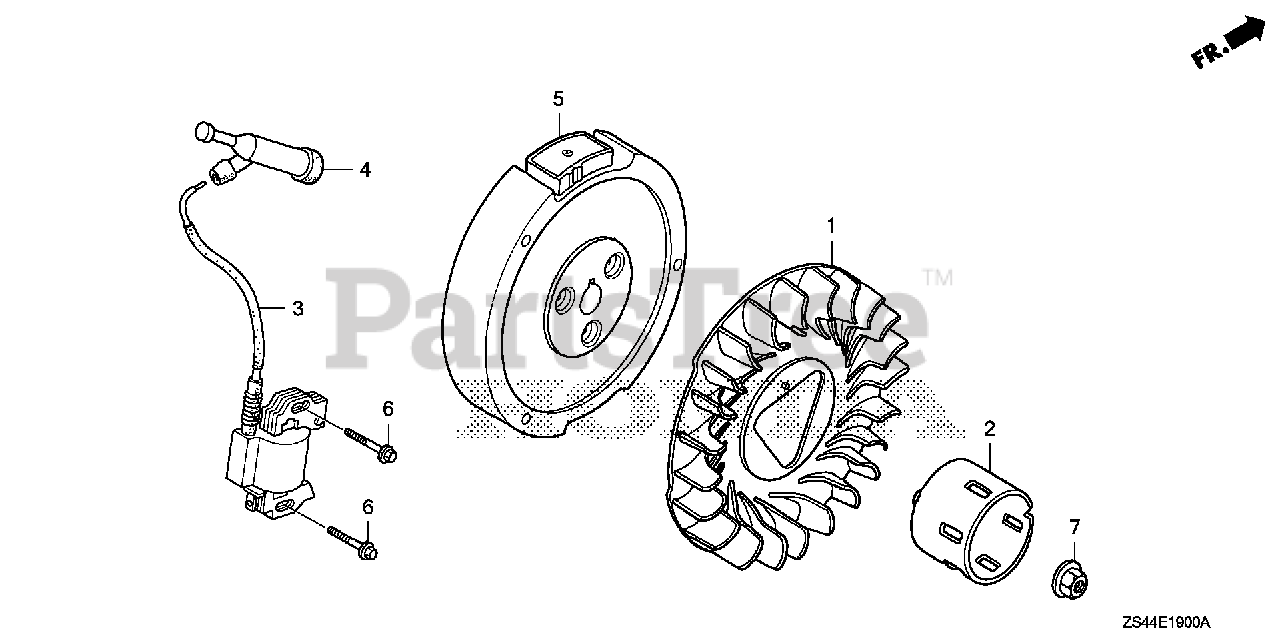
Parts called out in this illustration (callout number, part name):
1	FAN, COOLING
2	PULLEY, STARTER
3	COIL ASSY., IGNITION
4	CAP ASSY., NOISE SUPPRESSOR (NICHIWA Y-EZ RTFM256)
6	BOLT, FLANGE (6X28) (CT200)
7	NUT, SPECIAL (16MM)
